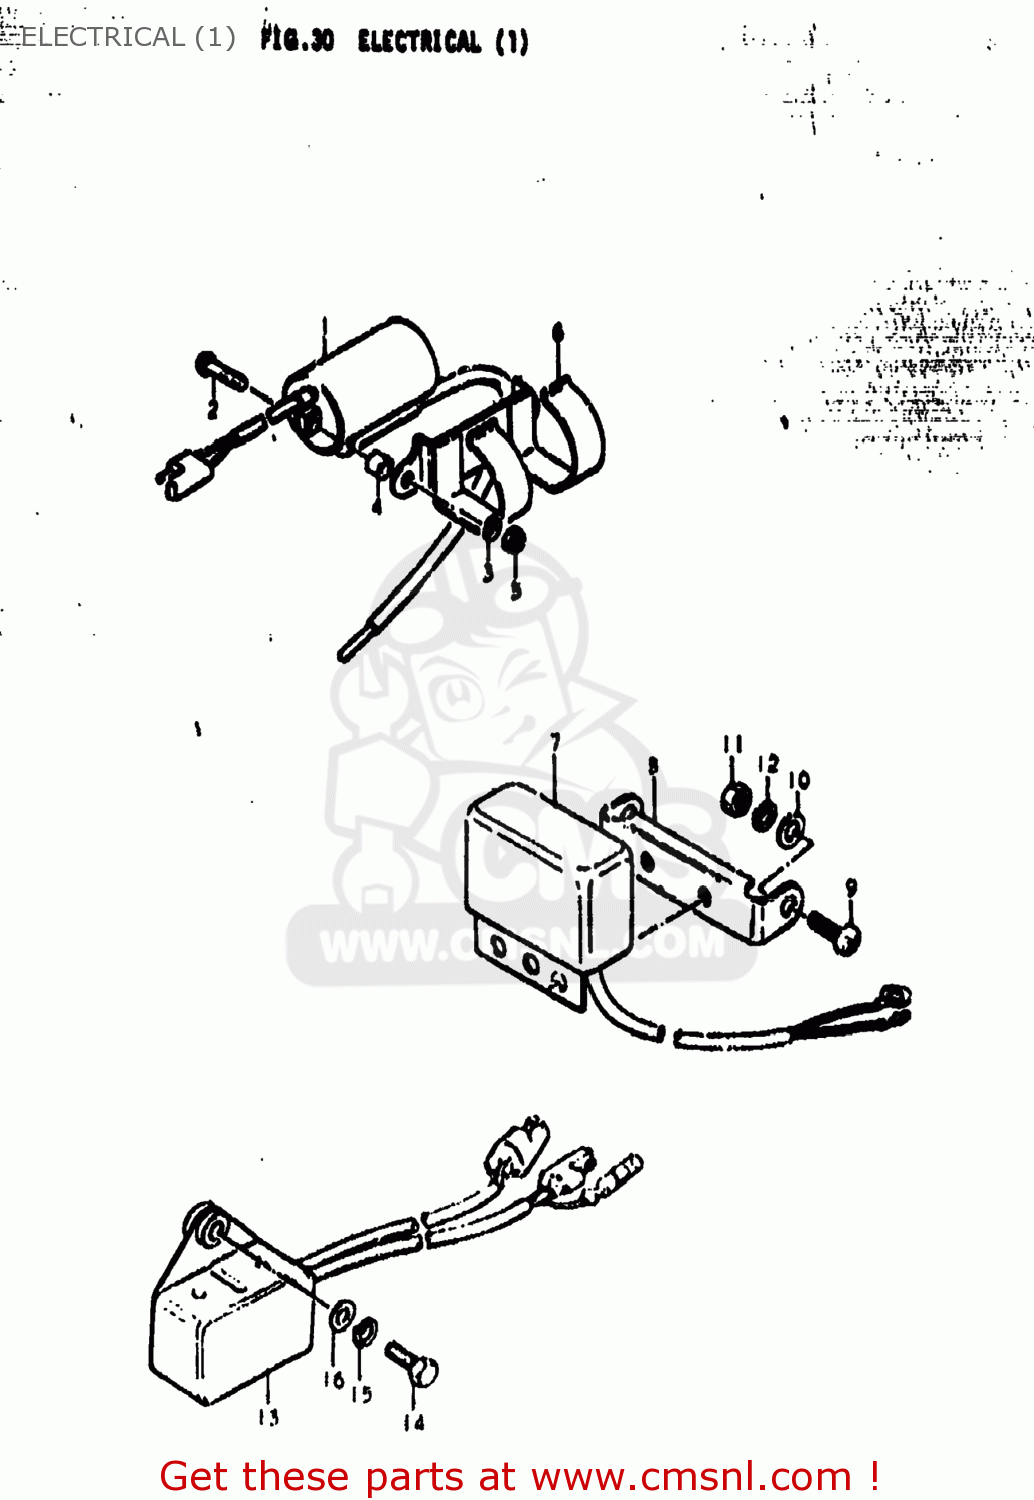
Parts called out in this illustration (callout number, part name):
1	COIL ASSEMBLY,IGNITION
2	SCREW
3	LOCK WASHER
4	SPACER
5	NUT
6	CLAMP
7	REGULATOR ASSEMBLY
9	SCREW 6X12
10	WASHER
11	NUT
12	LOCK WASHER
13	CDI UNIT ASSY
14	BOLT(6X20)
15	LOCK WASHER
16	WASHER
